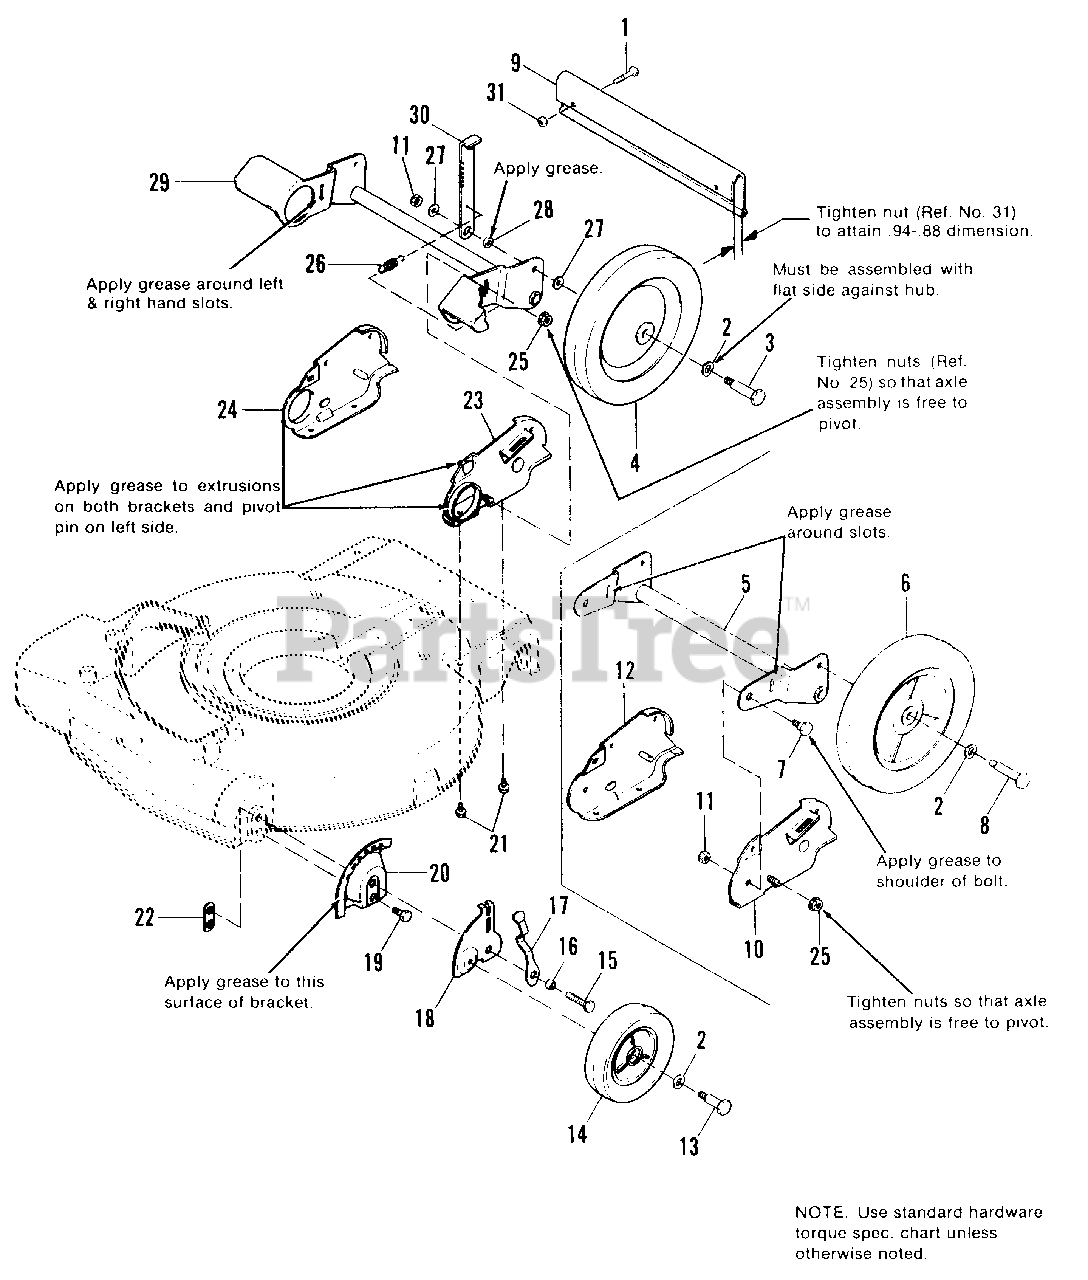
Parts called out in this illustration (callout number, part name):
1	CAPSCREW, Hex Hd., #10-24 x 1-1/2
2	WASHER, Special
3	BOLT, Wheel
4	WHEEL, 10"
5	PLATE & TUBE ASSY.
6	WHEEL, 10"
7	BOLT, Shoulder
8	BOLT, Wheel
9	SHIELD, Trailing
10	BRACKET ASSY., L.H.
11	LOCKNUT, Hex, Full, 3/8-16
12	BRACKET ASSY., R.H.
13	BOLT, Front Wheel
14	WHEEL, 6" Front
15	SCREW, Special, 3/8-16 x 1-3/4
17	SPRING, Height Adjustment
18	ADJUSTER, Height Front
19	CAPSCREW, Hex, 3/8-16 x 3/4
20	PLATE, Adjuster
21	SCREW, Taptite, 1/4-20 x 3/8
22	NUT, Pilot, Twin
23	BRACKET ASSY., L.H.
24	BRACKET ASSY., R.H.
25	LOCKNUT, Hex, Flange, 5/16-18
26	SPRING
27	WASHER, Plain, 5/16
28	SPACER
29	PLATE & TUBE ASSY.
30	ADJUSTER, Height, Rear
31	LOCKNUT, Hex, Nylon, #10-24
